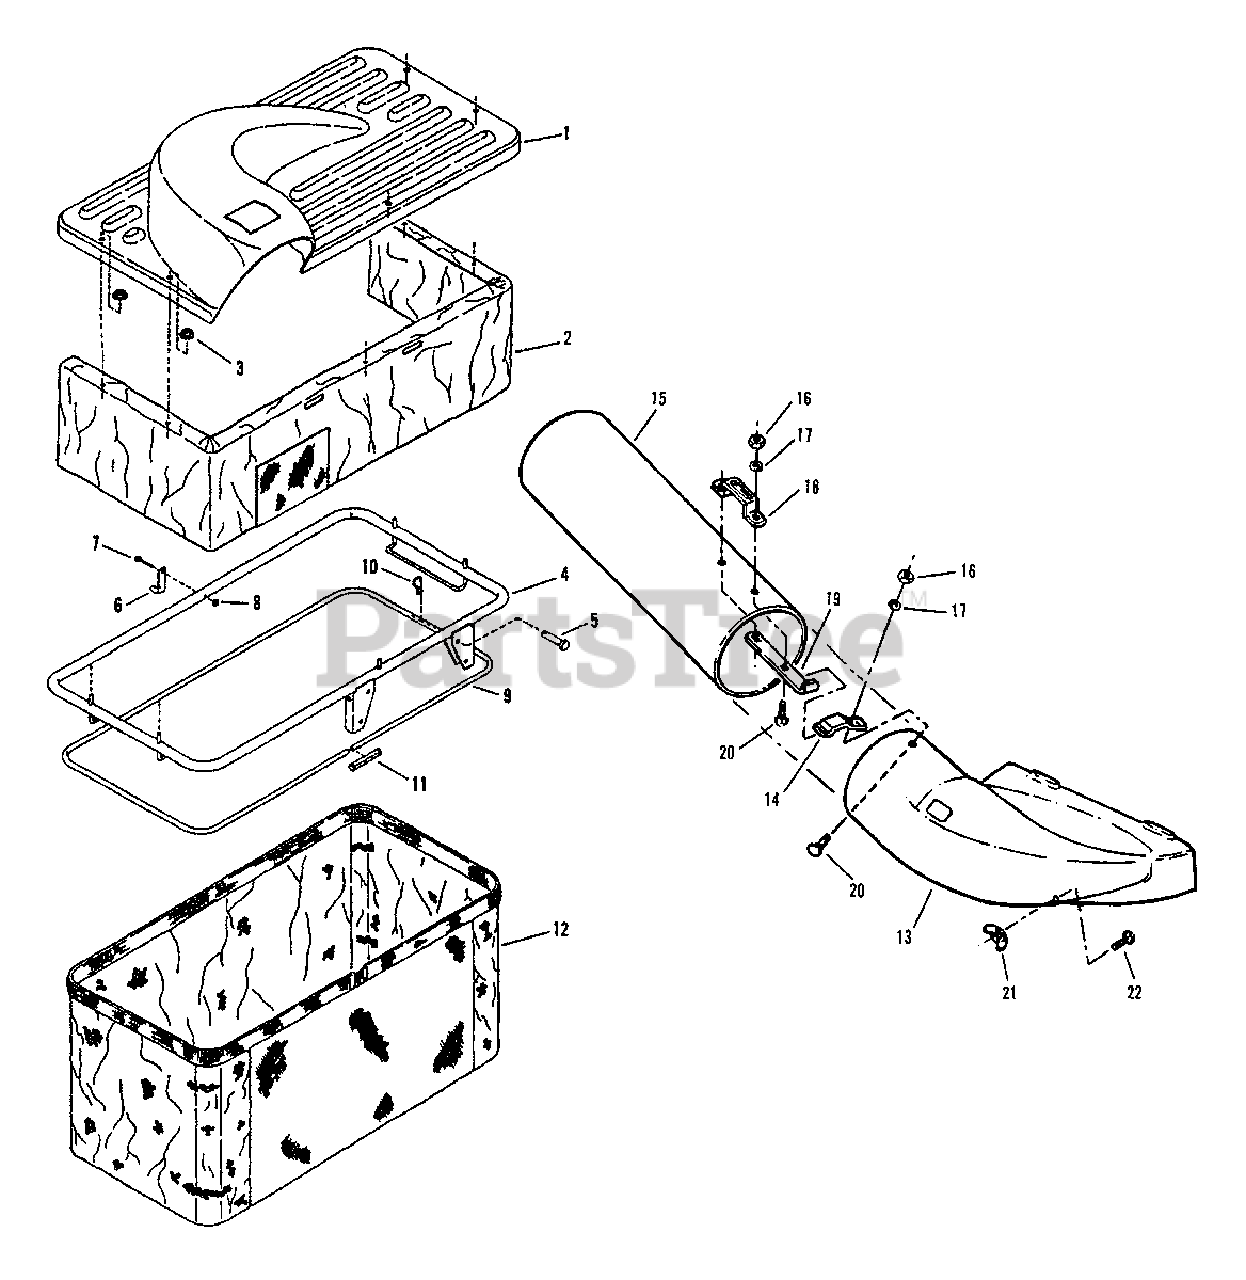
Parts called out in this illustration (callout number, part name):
1	TOP, Container
2	SKIRT, Dust
3	WASHER, Faceted
4	FRAME, Grass Bag
5	CLEVIS PIN, 5/16 x 1-11/16
6	LATCH, Grass Catcher
7	SCREW, 10-32 x 1-11/16 Hex Cap
8	NUT, 10-32 Hex Lock w/Nylon Insert
9	ROD, Bag
10	PIN, 3/32 x 1-1/2 Hair
11	CONNECTOR, 1/2 x 3" Rod
12	BAG, Single Zipperless
13	ADAPTER, Bag
14	LATCH, Tube
15	TUBE, Grass
16	NUT, 1/4-20 Hex
17	WASHER, 1/4 Lock
18	HANDLE, Tube
19	BASE, Handle
20	BOLT, 1/4-20 X 3/4"
21	WING-NUT, 5/16-18 Lock
22	BOLT, 5/16-18 X 1" Carriage
